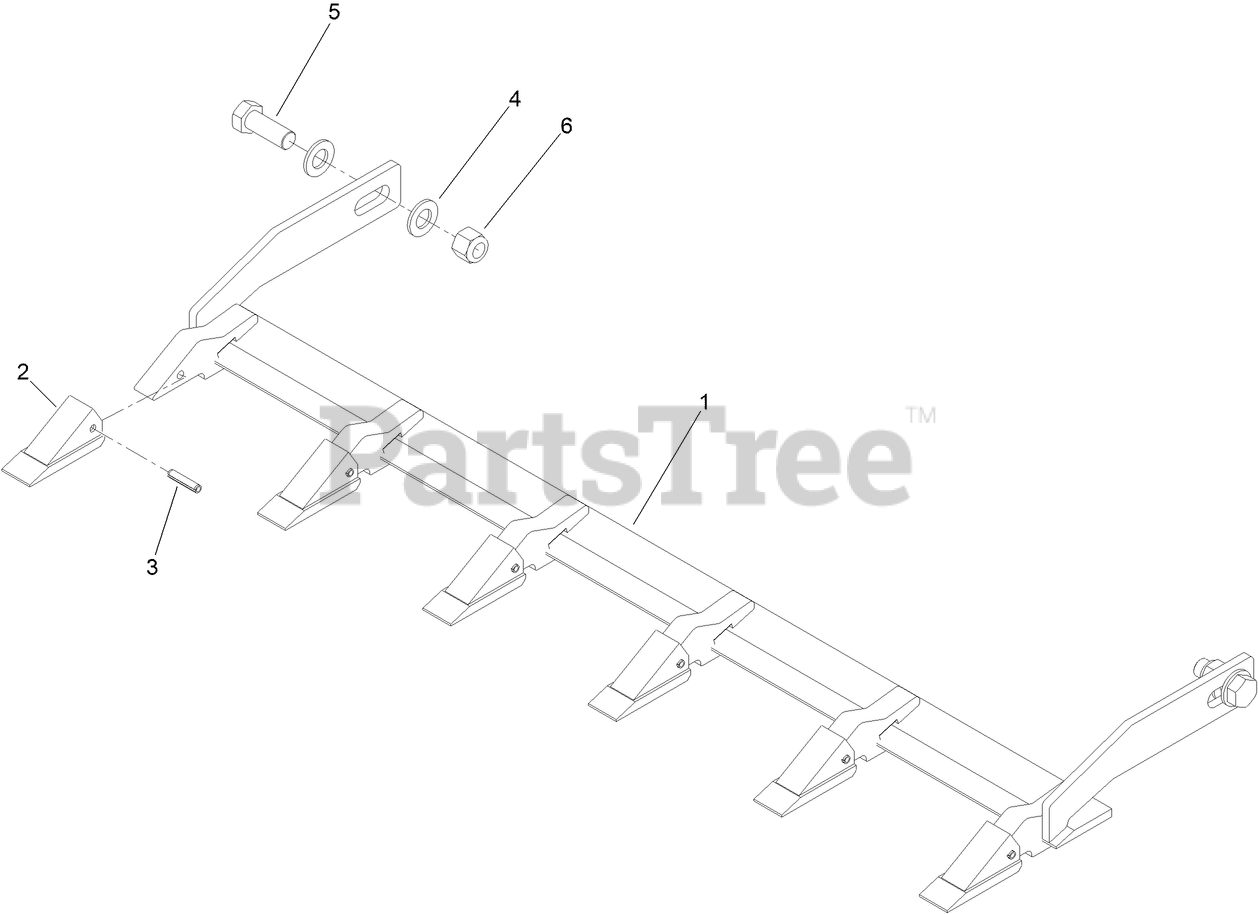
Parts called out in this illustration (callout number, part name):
1	TOOTH BAR ASM,
2	TOOTH-BUCKET
3	PIN-ROLL
4	WASHER-FLAT
5	SCREW-HH
6	NUT-LOCK, NI
